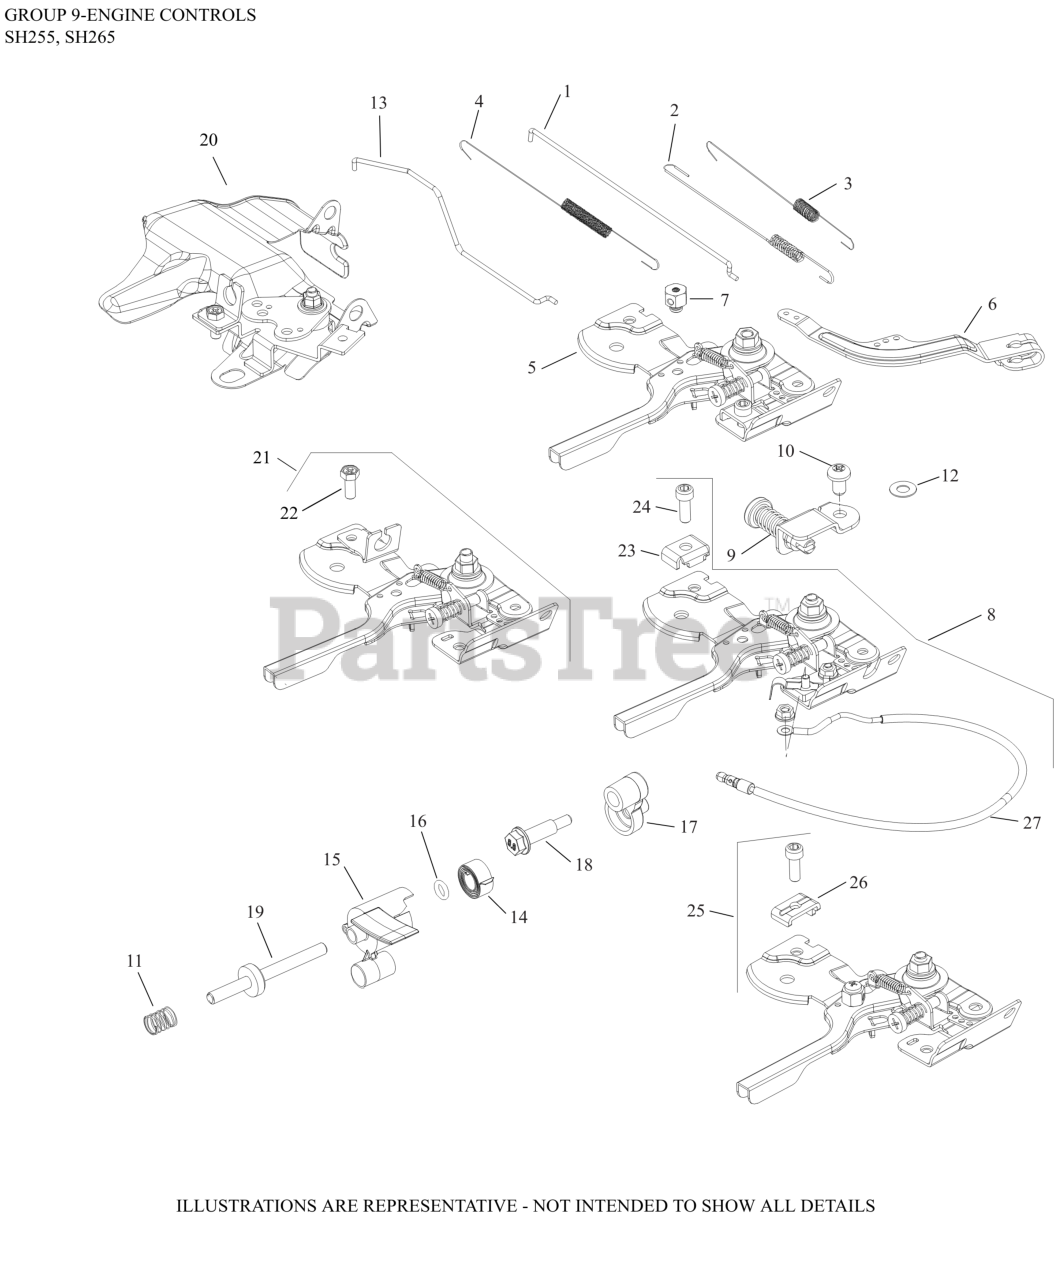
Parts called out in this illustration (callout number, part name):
1	LINKAGE, GOVERNOR-USE 18 079 05-S
2	SPRING, GOVERNOR
4	SPRING, LINKAGE
6	KIT, GOVERNOR LEVER
7	KIT, CABLE CLAMP
NI	CLAMP, CABLE
